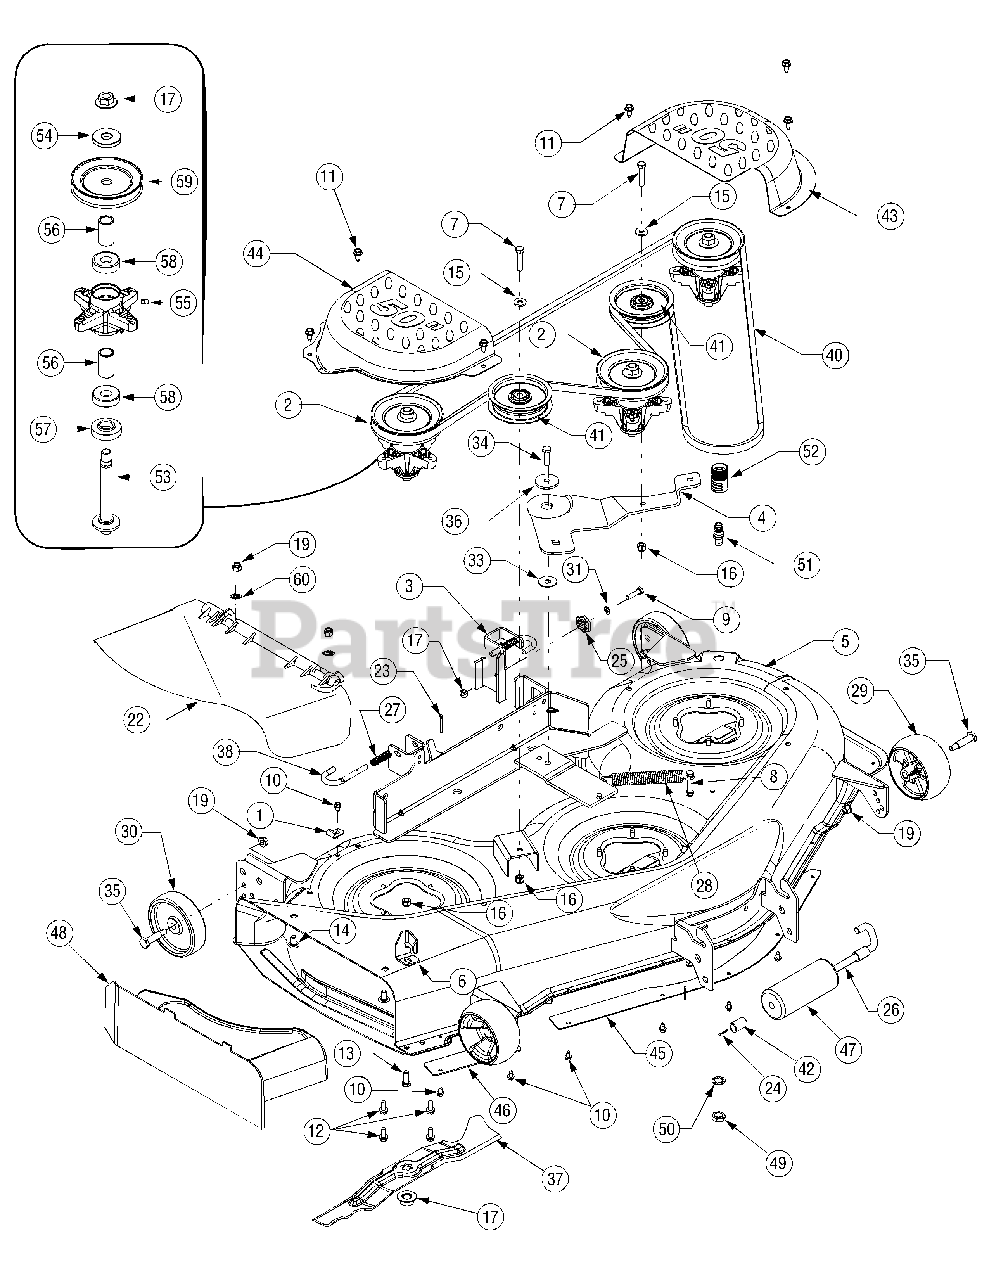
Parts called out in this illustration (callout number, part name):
1	Hook, Retainer
2	Spindle Assembly
7	Screw, 3/8-16, 1.75
8	Screw, 5/16-18 x 2.00
9	Screw, 5/16-18, 1.25, Gr5
10	Screw, 1/4-20 x 0.5
11	Screw, 5/16-18 x .75
12	Screw, 5/16-18 x .75
13	Screw, 3/8-16 x 1.0
14	Screw, Carriage, 3/8-16 x .75
15	Washer, Flat, .406 x .875 x .059
16	Nut, Nylon Lock, 3/8-16
17	Nut, Hex, Flange, 5/8-18
18	Nut, Nylon Lock, 5/16-18
19	Nut, Flange Lock, 3/8-16
20	Nut, Hex, 5/16-18, Gr5
21	Nut, 7/16-14
22	Chute Assembly, Side Discharge
23	Pin, Cotter, 1/8 x 1.25
24	Pin, Cotter, 3/32 x 1.25
25	Deck Adjustment Gear
26	Roller Pin
27	Spring, Compression, .531 x 1.75
28	Spring, Extension, .94 x 6.74
29	Deck Wheel, 5.0
30	Deck Wheel, 5.0
31	Washer, Lock, 5/16
32	Washer, Bell, .45 x 1.0 x .062
33	Washer, Flat, .442 x 1.38 x .060
34	Screw, 3/8-16, 1.25
35	Shoulder Screw .498 x 1.53 x 3/8-16
35	Shoulder Bolt, .50 x 2.5 x 3/8-16
36	Spacer, Shoulder, .884 x .190
37	Blade, 17.90
38	Rod, Deck Release .375 Dia.
39	Spacer, .550 x .755 x 1.1
40	Belt, V-Type, Aramid
41	Pulley, Idler, 3.5"
42	Spacer, 1.1"
48	Baffle, Mulch
49	Nut, Hex, M16-1.5
50	Washer, Lock
51	Port, Water
52	Coupler, Hose
53	Shaft, Spindle, 5.75
54	Washer, Flat, .760 x 1.5 x .120
55	Lube Fitting, 3/16
56	Spacer, .800 x 1.10 x 1.322
57	Spacer, 79 x 1.84 x .55
58	Ball Bearing, .787 x 1.85 x .551
59	Pulley, 5.39"
